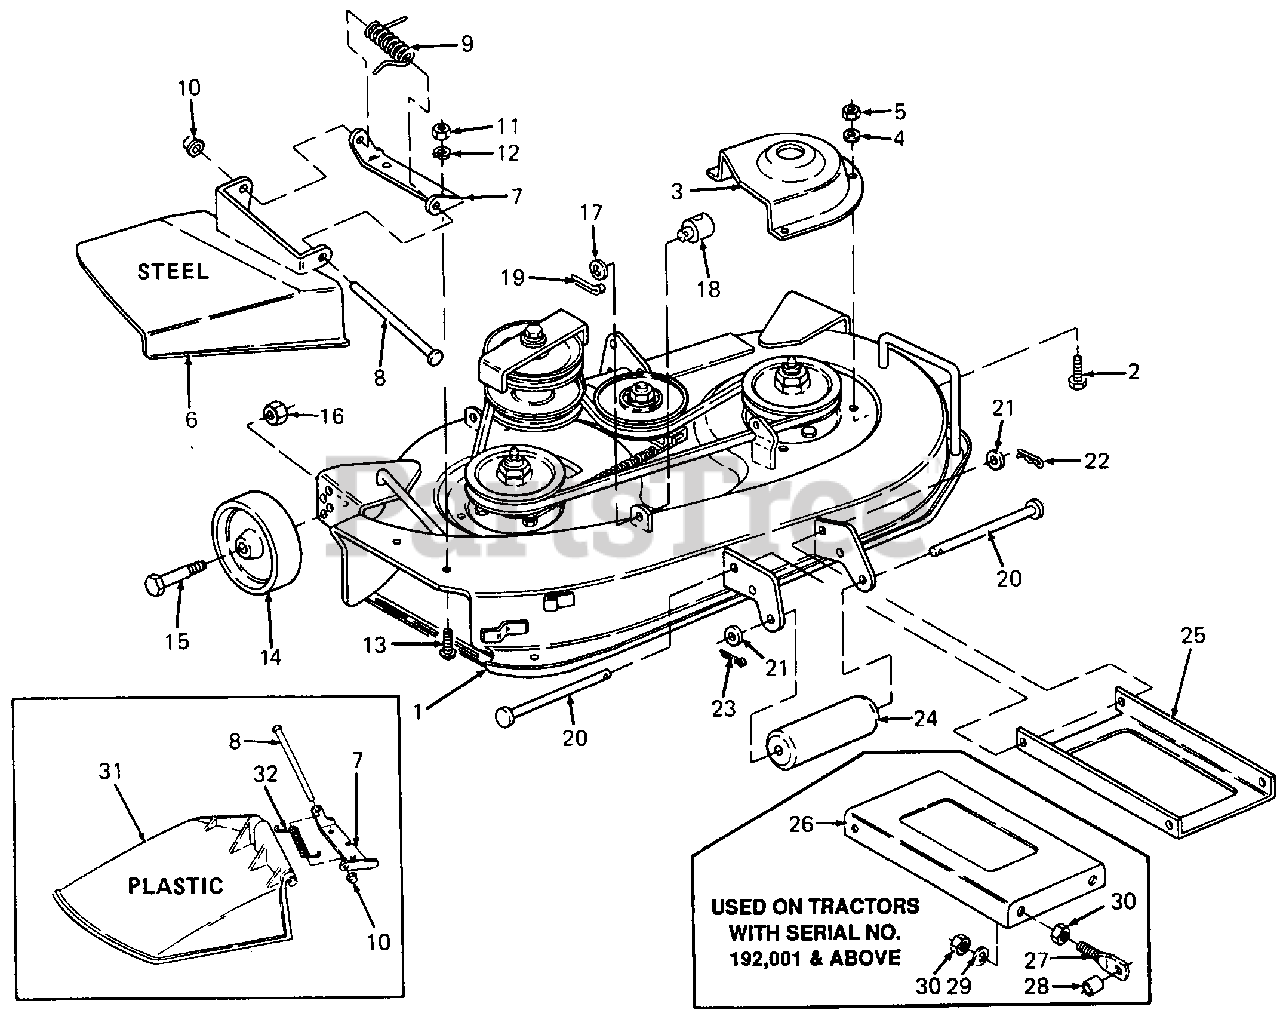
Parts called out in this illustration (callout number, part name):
1	Deck w/Graphics
2	Screw, Hex Cutting, 5/16-18 X .62 Lg
3	Cover, Belt
4	Washer, Flat, .34 X .68 X .06 Thk
5	Nut, Hex, 5/16-18 GR5
6	Chute Kit, w/ Graphic (Steel)
7	Bracket, Hinge Mounting
8	Pin, Hinge, .25 Dia X 4.9 Lg
9	Spring, Torsion
10	Nut, Cap Speed
11	Nut, Hex Jam, 1/4-20
12	Washer, Lock, 1/4
13	Screw, Truss Machine, 1/4-20 X .50 Lg
14	Wheel, Gage, 5 in. Dia
15	Screw, Shoulder
16	Nut, Hex Center Lock Jam, 3/8-16
17	Washer, Flat, .406 X .750 X .06 Thk
18	Ferrule
19	Pin, Cotter
20	Pin, Clevis, 1/2 Dia X 7.68 Lg
21	Washer, Flat, .510 X 1.0 X .06 Thk
22	Pin, Internal Cotter
23	Pin, Cotter
24	Roller, Front
25	Bracket, Deck Front Support
26	Bracket, Deck Front Support
27	Eye Bolt
28	Sleeve
29	Washer, Lock, 1/2
30	Nut, Hex, 1/2-13 GR5
31	Chute Kit w/Graphic (Plastic)
32	Spring, Torsion
